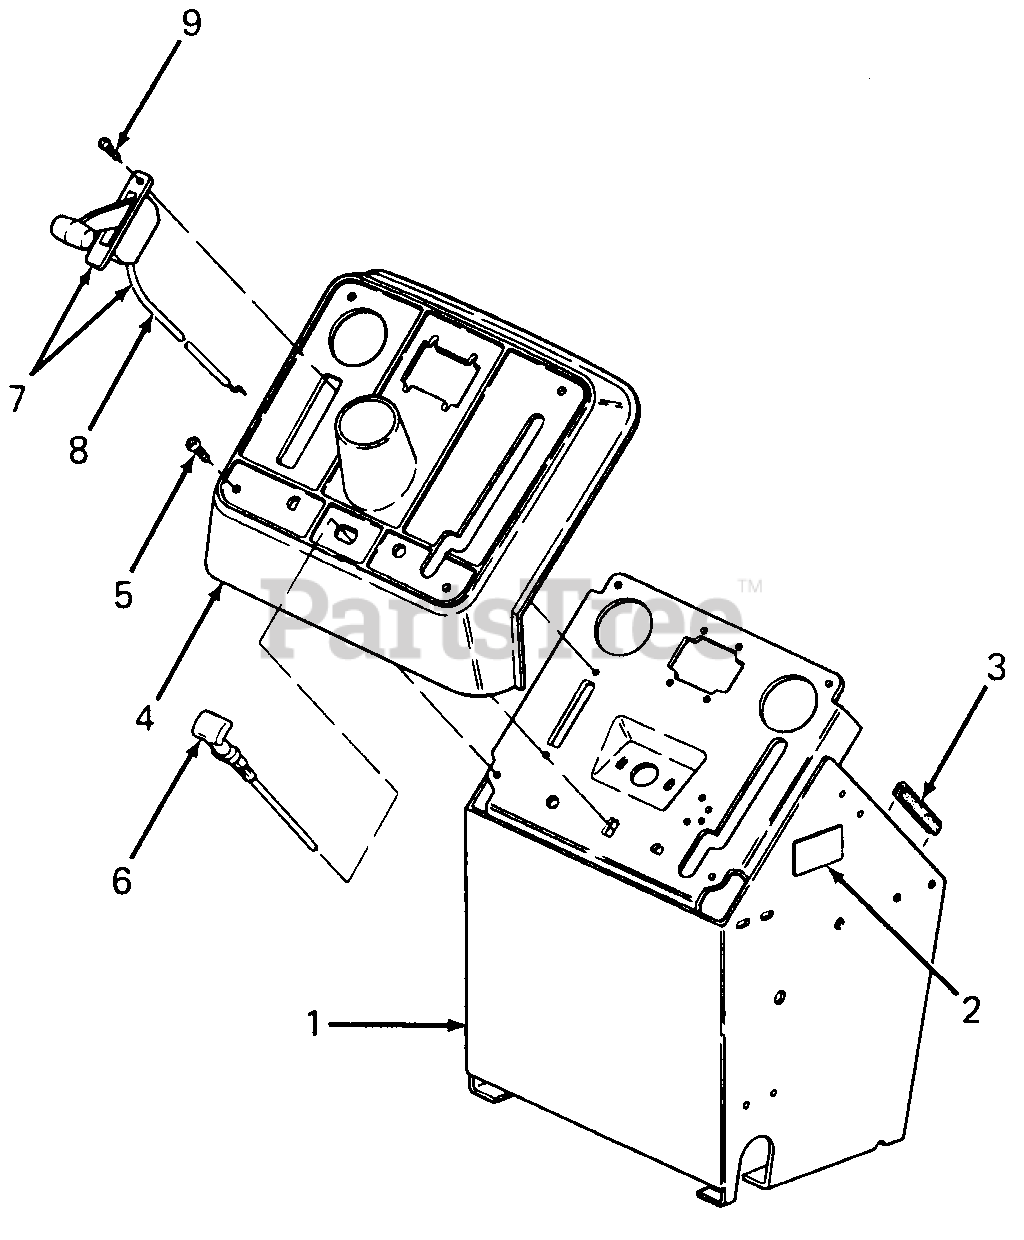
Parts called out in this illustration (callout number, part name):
2	Label, Booster Battery
3	Trim Strip, 4.0 Lg
4	Panel, Dash
5	Screw, Pan Hd Cutting, #10-24 X .75 Lg
6	Control, Choke
7	Control Assy, Throttle, Complete
8	Wire, Throttle Control
9	Screw, Truss Mach AB Tapp, #10 X .50 Lg
